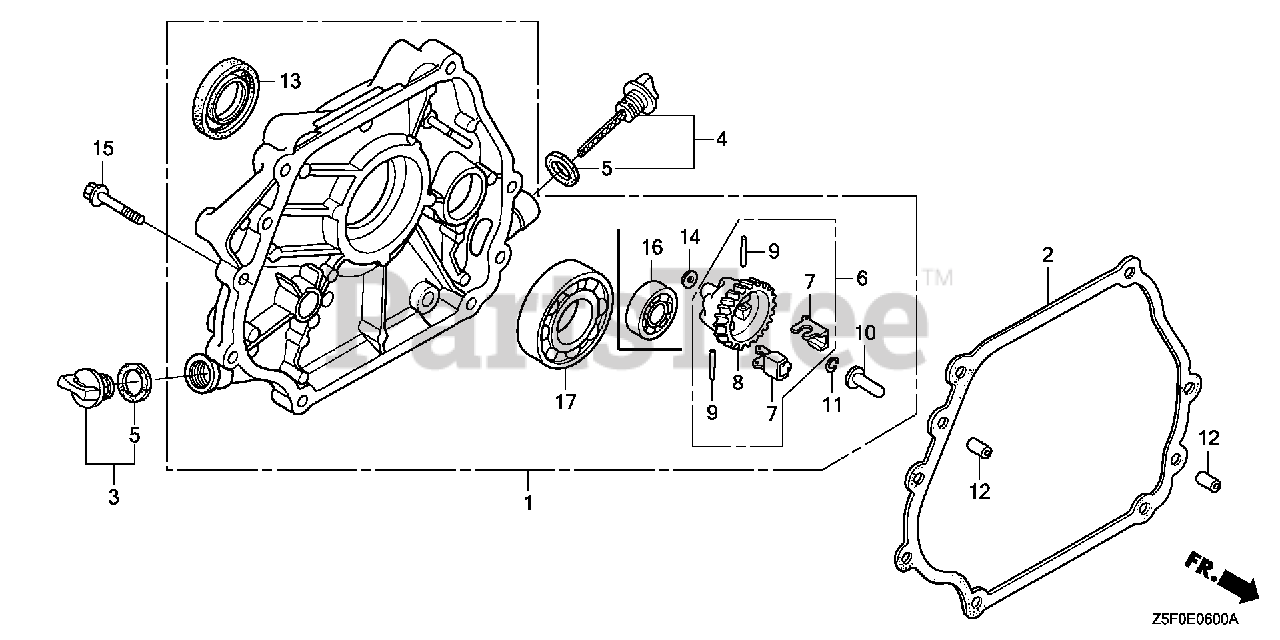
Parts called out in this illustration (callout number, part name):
1	COVER ASSY., CRANKCASE
2	GASKET, CASE COVER
3	CAP ASSY., OIL FILLER
4	CAP ASSY., OIL FILLER
5	GASKET, OIL FILLER CAP
6	GOVERNOR ASSY. (BALANCER)
7	WEIGHT, GOVERNOR
8	HOLDER, GOVERNOR WEIGHT
9	PIN, GOVERNOR WEIGHT
10	SLIDER, GOVERNOR
11	CLIP, GOVERNOR HOLDER
12	PIN, DOWEL (8X12)
13	OIL SEAL (30X46X8)
14	WASHER, PLAIN (6MM)
15	BOLT, FLANGE (8X35)
16	BEARING, RADIAL BALL (6202)
17	BEARING, RADIAL BALL (6206)
